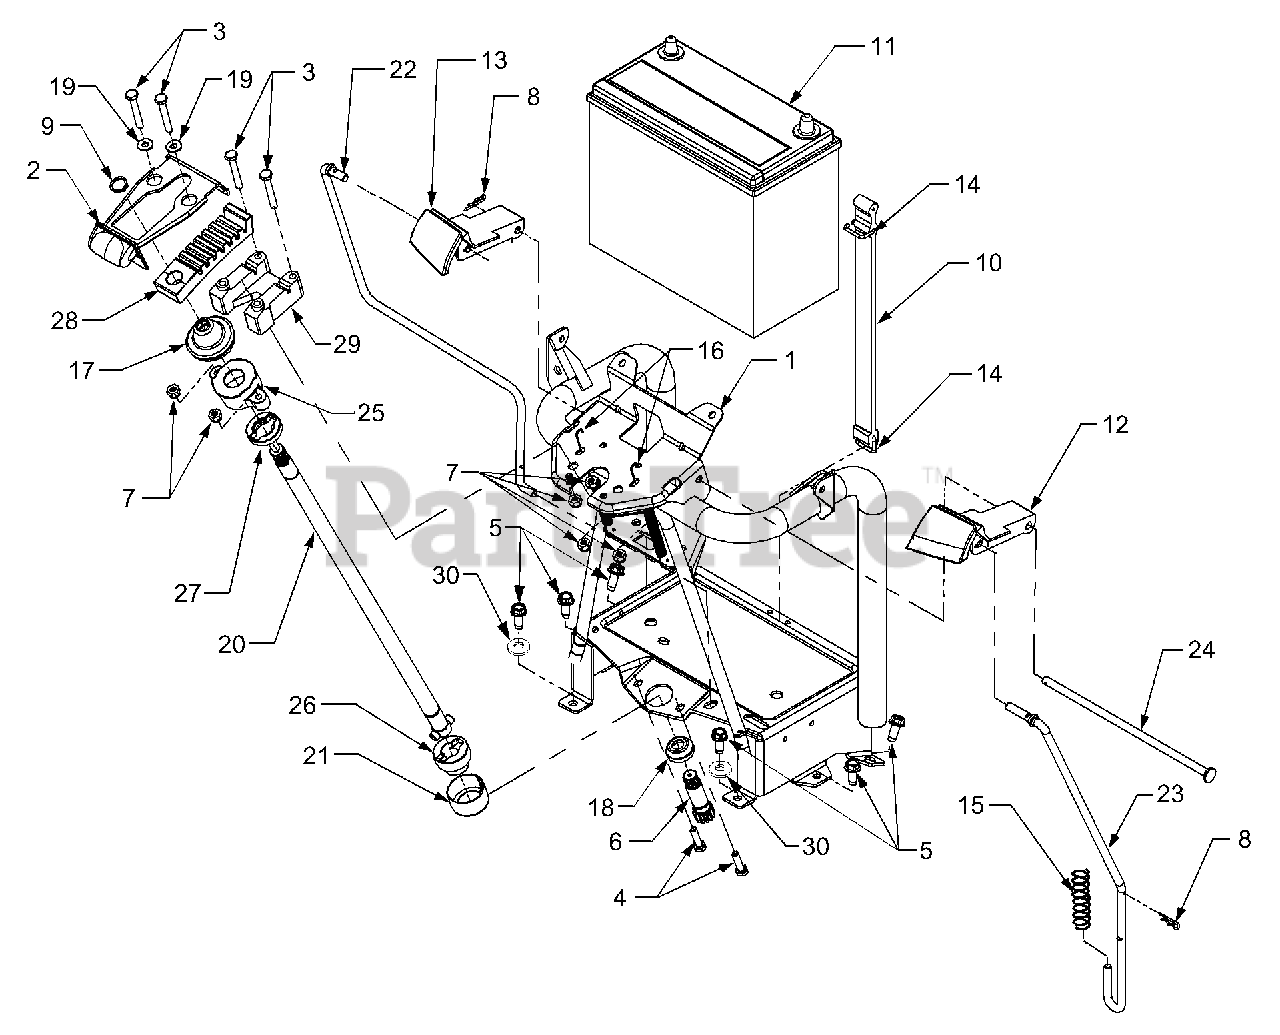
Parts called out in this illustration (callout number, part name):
1	Pedestal Assembly
2	Handle, Tilt
3	Screw, Hex Cap 1/4-20 x 1.75 GR5
4	Screw, Hex Cap 1/4-20 x 1.0 GR5
5	Screw, Hex Wash. Hd. Tapp 5/16-18 x .75
6	Shaft, Lower Steering
7	Nut, Hex Insert Lock, 1/4-20
8	Pin, Internal Cotter
9	Ring, Retaining, .56 Dia Shaft
10	Strap, Battery
11	Battery
12	Lever, Park Brake
13	Lever, Cruise
14	Hook, Wire Rectangular
15	Spring, Compression, .676 x 2.57
16	Spring, Extension
17	Boot, Tilt Wheel Coupling
18	Boot, Shaft Cover
19	Washer, Flat, .271 x .63 x .065
20	Shaft, Upper Steering
21	Bearing, Sleeve, 1.44 x 1.5 x .812
22	Rod, Cruise Control
23	Rod, Parking Brake
24	Rod, Cruise/Brake Pivot
25	Housing, Tilt Wheel Coupling
26	Coupling Half, Bottom
27	Coupling Half, Top
28	Index, Tilt Steering
29	Block, Tilt Steering
30	Washer, Flat, .344 x .688 x .065
